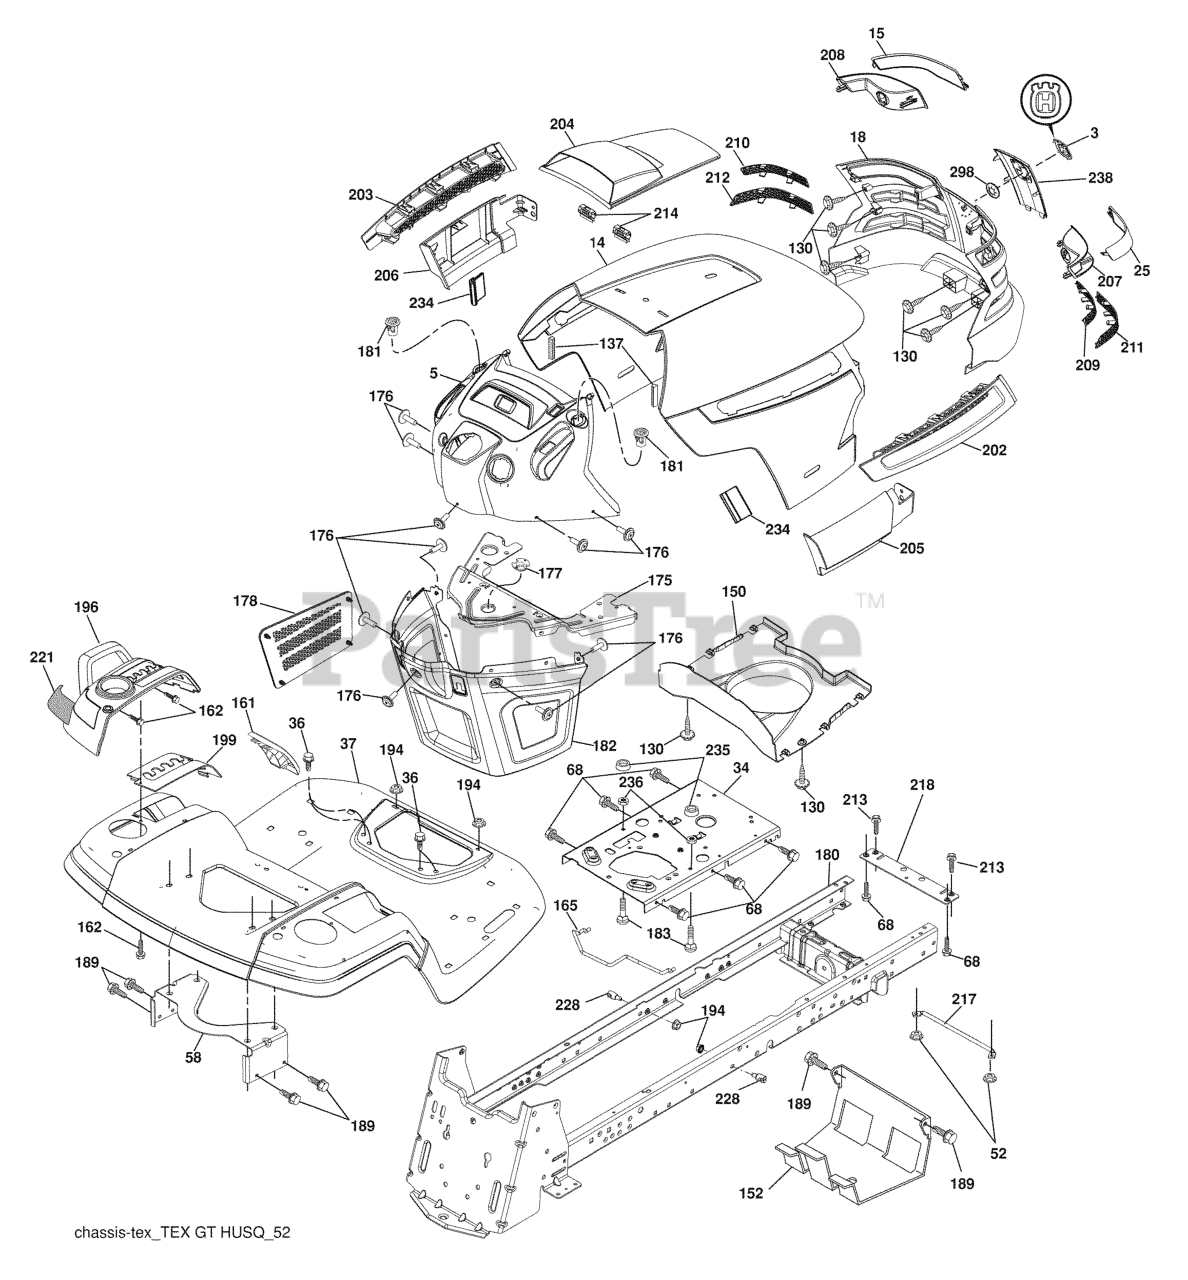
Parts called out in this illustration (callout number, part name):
3	RP LOGO
5	DASH.ASM.GTHUSQTX.RGS.ELECT.CK
14	HOOD
15	LENS.LH.TEX.GT.HUSQ.CL
18	GRILL.ASM.HUSQ.TG/CRD.W/TRIM
25	LENS.RH.TEX.GT.HUSQ.CL
34	PLATE.ENGINE.WELDED.CHASSIS
36	SCREW 5/16"
37	FENDER.PNT.TX.GT.CH/FW.ORANGE
52	LOCKNUT
58	BRKT.SUPPORT.FNDR/TANK
68	Screw 5/16-18 x 1/2
130	SCREW.#10 X 0.750.BOS
137	BUMPER DASH
150	AIR.DUCT.HOOD.TEX.GT.HUSQ
152	SHIELD.BROWNING.W/TEX
161	CONSOLE.FUEL.WINDOW.HU
162	SCREW.HI-LO.CONSOLE
165	SUPPORT.TANK.REAR.W/TEX
175	PLATE.CROSSMEMBER.HUSQ
176	SCREW.#10-24X5/8.RN.QU
177	BUSHING, STEERING
178	CARGO.ASM.NET.TXGT.W/C
180	CHASSIS.GT.SLOPED.DRAWBAR.
181	BUSHING.MNT.FEND.CRGO.
182	DASH.LOWER.COMMON.12V.ADAPTOR
183	BOLT.5/16-18X1-1/4 FULL.THREAD
189	SCREW
194	NUT LOCK HEX FLANGE 5/16-18
196	CONSOLE.ASM.DCKLFT.W/RF.HQ.DLR
199	PLATE.DECK.LIFT.HUSQVARNA.GT
202	VENT.SIDE.HOOD.HUSQ.RH.GREY
203	VENT.SIDE.HOOD.HUSQ.LH.GRAY
204	HOOD VENT
205	SKIRT.HOOD.SIDE.HUSQ.RH.GREY
206	SKIRT.HOOD.SIDE.HUSQ.LH.GREY
207	BEZEL.RH.TEX.GT.HUSQ
208	BEZEL.LH.TEX.GT.HUSQ
209	INSERT.HEX.GRILL.HUSQ.GREY
210	INSERT.HEX.GRILL.HUSQ.
211	INSERT.HEX.GRILL.HUSQ.
212	INSERT.HEX.GRILL.HUSQ.
213	BOLT
214	CLIP.RETAINER.TINNER.
217	ROD.PIVOT.HOOD
218	X-PIECE.HOOD.STOP.NON/
221	REFLECTOR.LH.TEX GT HU
228	STUD.FASTNER.W/ANTI-ROTATE
234	BUMPER.HOOD.TEX.HUSQVARNA
235	SPACER FENDER
236	NUT.CENTERLOCK.5/16-
238	TRIM.HUSQ.TG/CRD.SERVICE
298	NUT PUSH M
